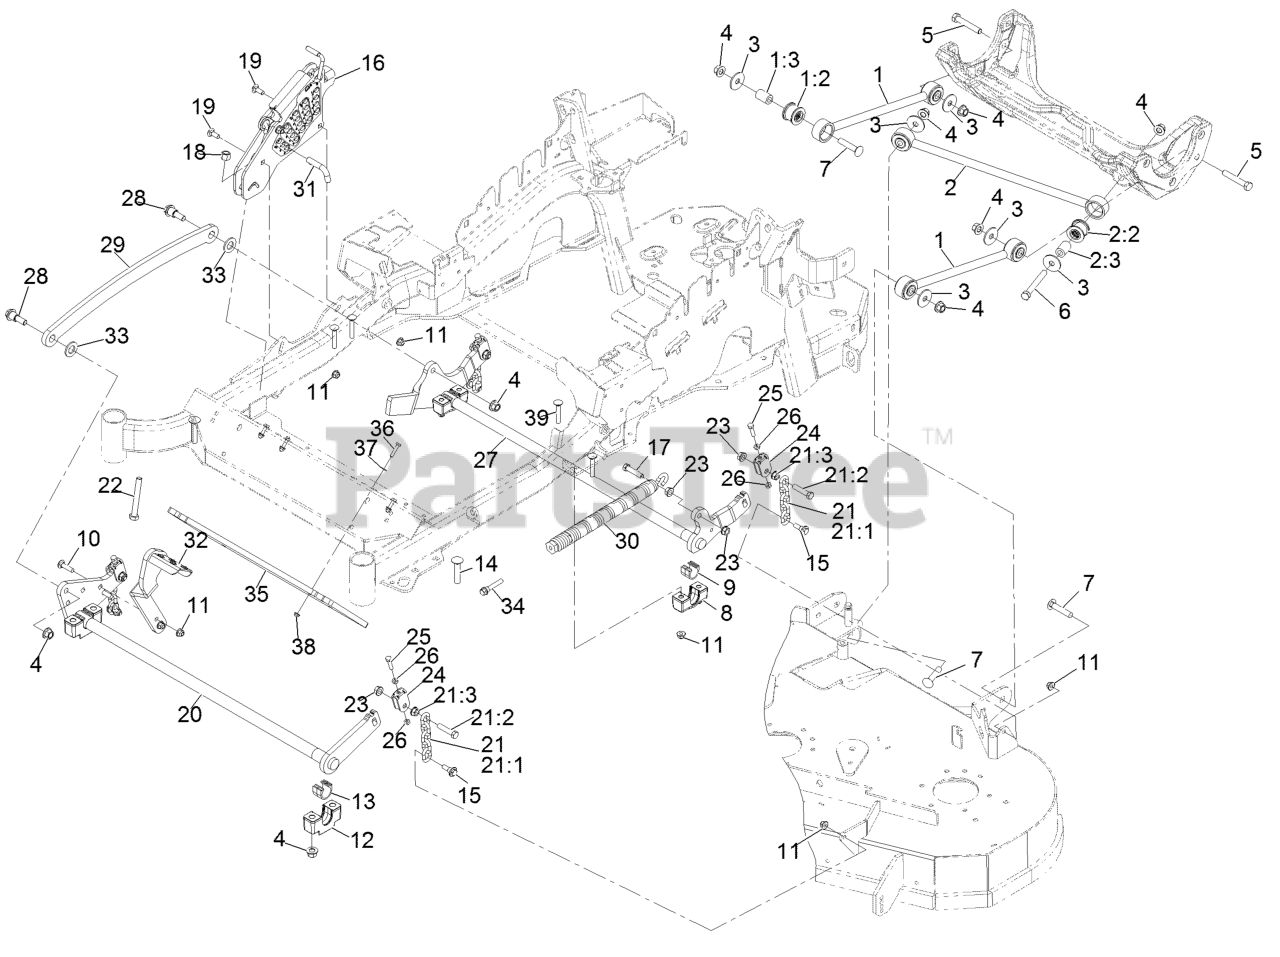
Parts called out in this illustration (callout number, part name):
1	Deck Strut ASM
1:2	Bushing-Suspension, Rubber
2	Panhard Rod ASM
2:2	Bushing-Suspension, Rubber
4	Nut-Lock 1/2-13
5	Screw-HH 1/2-13 X 3
6	Screw-HH 1/2-13 X 4
7	Bolt-Carriage 1/2-13 X 2 1/2
8	Support-Cross Shaft, Bearing Rear
9	Bearing-Cross Shaft, Rear
10	Bolt-Carriage 3/8-16 X 1 1/2
11	Nut-Nyloc 3/8-16 Flg
12	Support-Cross Shaft, Bearing
13	Bearing-Cross Shaft, Front
14	Bolt-Carriage 1/2-13 X 2 1/2 Spl Neck
15	Screw-Hex Flange 3/8-16 X .80
16	HOC ASM
17	Screw-HH 7/16-14 X 2
18	Nut-Nyloc 1/2-13
19	Bolt-Carriage 3/8-16 X 1
20	Decklift-Front
21	Deck Lift Chain ASM
21:1	Chain-Lift, Deck
21:2	Screw-HH 7/16-14 X 2
21:3	Nut-Whizlock 7/16-14
22	Bolt-HH 1/2-13 X 4 Tap
23	Nut-Whizlock 7/16-14
24	Yoke-Adjust, Deck
25	Screw-HH 5/16-18 X 1 1/4
26	Nut-Jam 5/16-18
27	Lift-Deck, Rear
28	Screw-Shoulder HHF 1/2-13 X 1.12
29	Link-Lift, Deck
30	Extension Spring ASM
31	Pin-HOC
32	Lever-Foot
33	Washer-3/4 Sae
34	Screw-Shcs 3/8-16 X 2.212
35	Weight-Toe Board
36	Screw-HH 1/4-20 X 1 1/4
37	Washer-1/4 Sae
38	Nut-Nyloc 1/4-20 Flg
39	Bolt-Carriage 3/8-16 X 2 1/4
